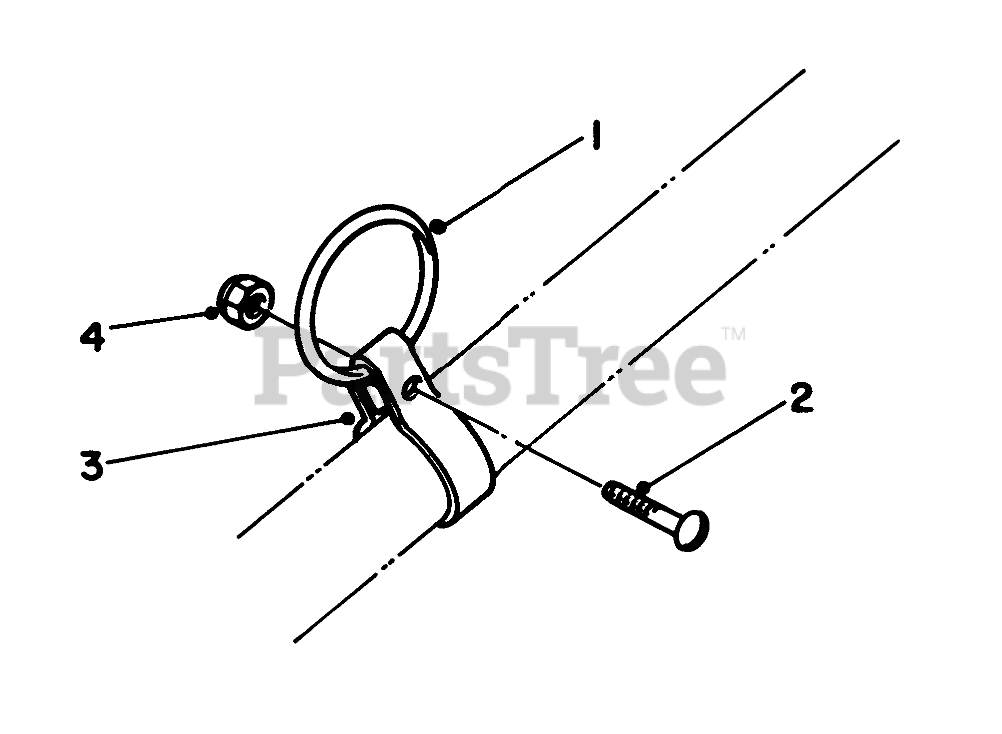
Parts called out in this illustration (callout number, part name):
1	Ring
2	SCREW-SRH
3	Clamp
4	NUT-LOCK, NI
